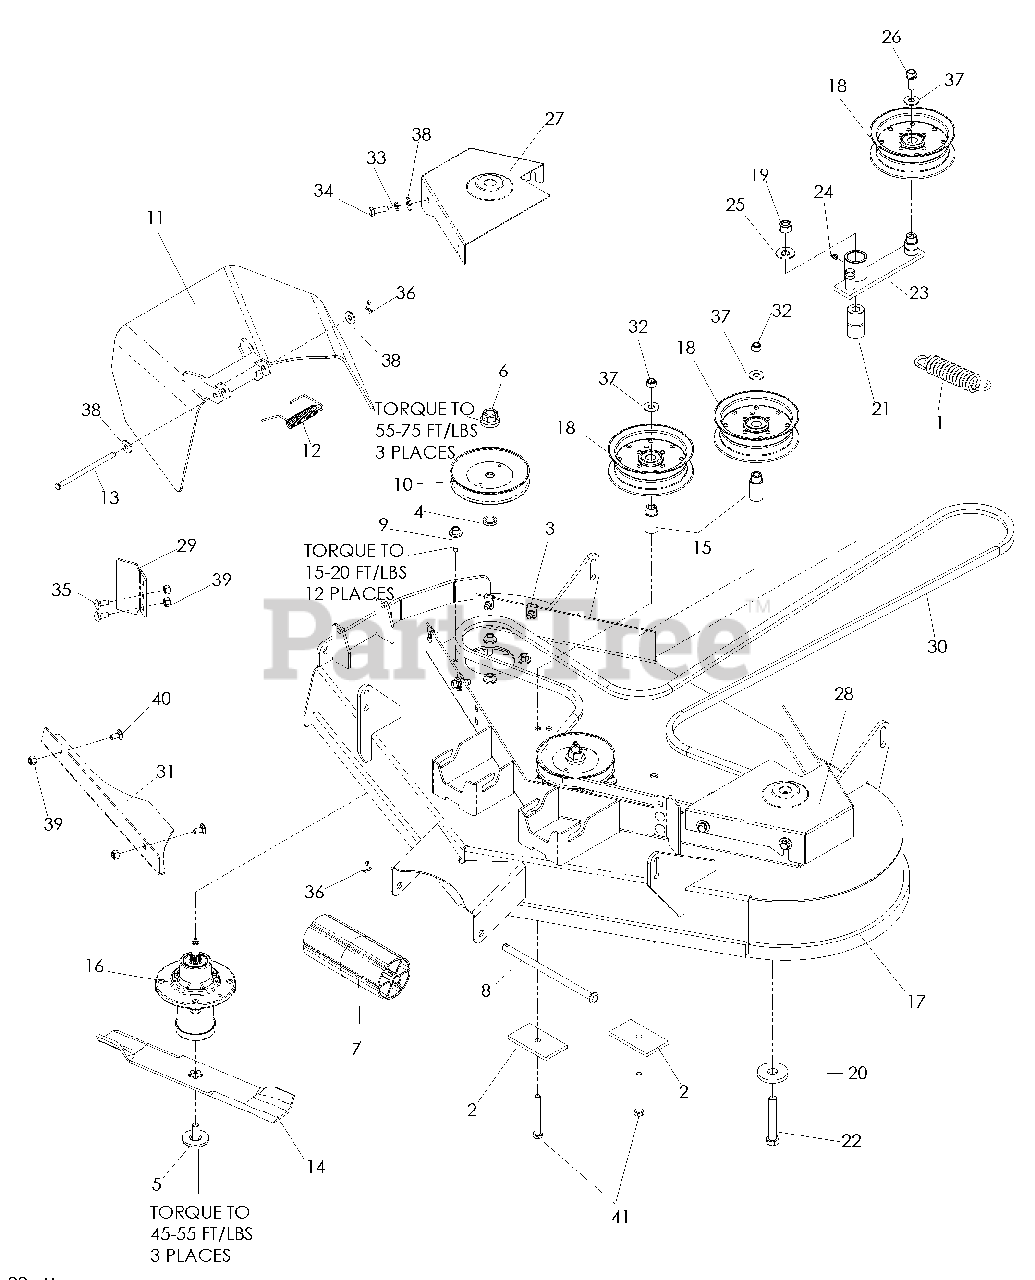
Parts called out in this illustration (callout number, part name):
1	SPRING, EXTENSION
2	PAD
3	NUT 5/16-18 U TYPE
4	WASHER .675 SPACER
5	BOLT 7/16 SPEC
6	NUT 9/16 CENTERLOCK
7	ROLLER, NOSE
8	ROD, ROLLER, NARROW
9	SCREW 5/16-18 x 1 3/8 WSH HD
10	PULLEY, MANDREL
11	DISCHARGE CHUTE
12	SPRING, TORSION
13	PIN-CLEVIS 5/16 DIA x 5.19
14	BLADE 14.625"
15	IDLER BUSHING
16	HOUSING ASSEMBLY
17	DECK W/DECALS
18	IDLER PULLEY, NYLON
19	NUT 1/2-13 NYLOC
20	WASHER .65 SUPPORT
21	BUSHING, PIVOT
22	HCS 1/2-13 x 3 1/4
24	ZERK, STRAIGHT 1/4-28
25	WASHER 9/16
26	HCS 3/8-16 x 1 WHIZLK
27	BELTSHIELD, RIGHT
28	BELTSHIELD, LEFT
31	CONFINEMENT PLATE
32	NUT 3/8-16 NYLOC
33	WASHER 5/16
34	HCS 5/16-18 x 1
35	RHSNB 5/16-18 x 3/4
36	PIN COTTER 1/8 x 3/4
37	WASHER 3/8
38	WASHER 5/16
39	NUT 5/16-18 NYLOC
40	RHSNB 5/16-18 x 5/8
41	HCS 3/8-16 x 3
